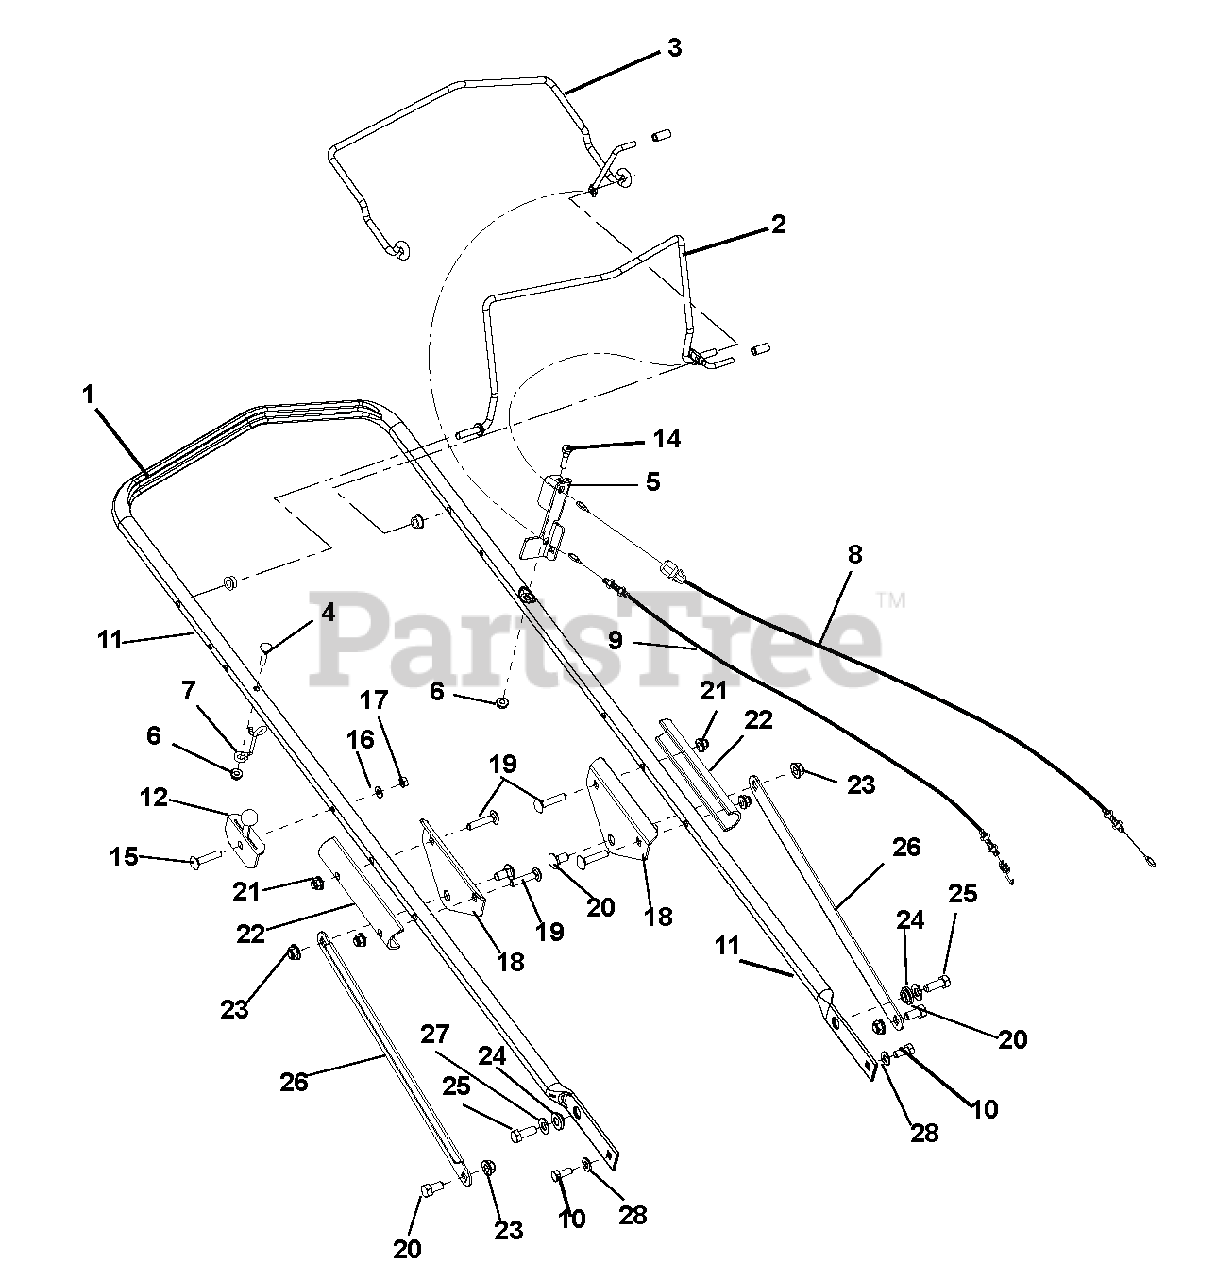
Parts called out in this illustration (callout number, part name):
1	HANDLEBAR,PRO 21
2	BAIL, OPERATOR PRESENCE
3	BAIL, CLUTCH
4	BLT-RDHDXLSQNK.25-20X1.25 G5ZC
5	ANCHOR, CABLE - THUMB ADJUST
6	@NUT-LK-TOP-FLG .25-20 YWZC
7	GUIDE - PULLCORD
8	CABLE, OPC GCV/GXV DBL BAIL
8	CABLE, TO BE REPLACED 12925
9	CABLE, XD DOUBLE BAIL DRIVE
10	@BLT-HEX .31-18X.75 GR5 YWZC
11	CONDUIT CLIP
12	CABLE- LM THROTTLE
13	PLATE,HINGE
14	@BLT-HEX .25-20X1.25 GR5 YWZC
15	BLT-RDHDSQNK .25-20X1.75 G5YZ
16	@WSHR-FL-STL.250X.56X.049 YWZC
17	@NUT-LK-CTR .25-20 YWZC
18	PLATE,HANDLEBAR
19	@BLT-RDHDSQNK .31-18X1.50 G5YZ
20	@BLT-HEX .38-16X.75 GR5 YWZC
21	@NUT-LK-NYL-FLG .31-18 YWZC
22	SERVICE BAR BRACE
23	@NUT-LK-NYL-FLG .38-16 YWZC
24	BSHG-FLG .406X.88X.270X.140
25	@BLT-HEX .38-16X1.00 GR5 YWZC
26	STRAP,HANDLEBAR
27	@WSHR-FL-STL.406X.812X.065 YWZ
28	@WSHR-FL-STL.344X.688X.065YWZC
